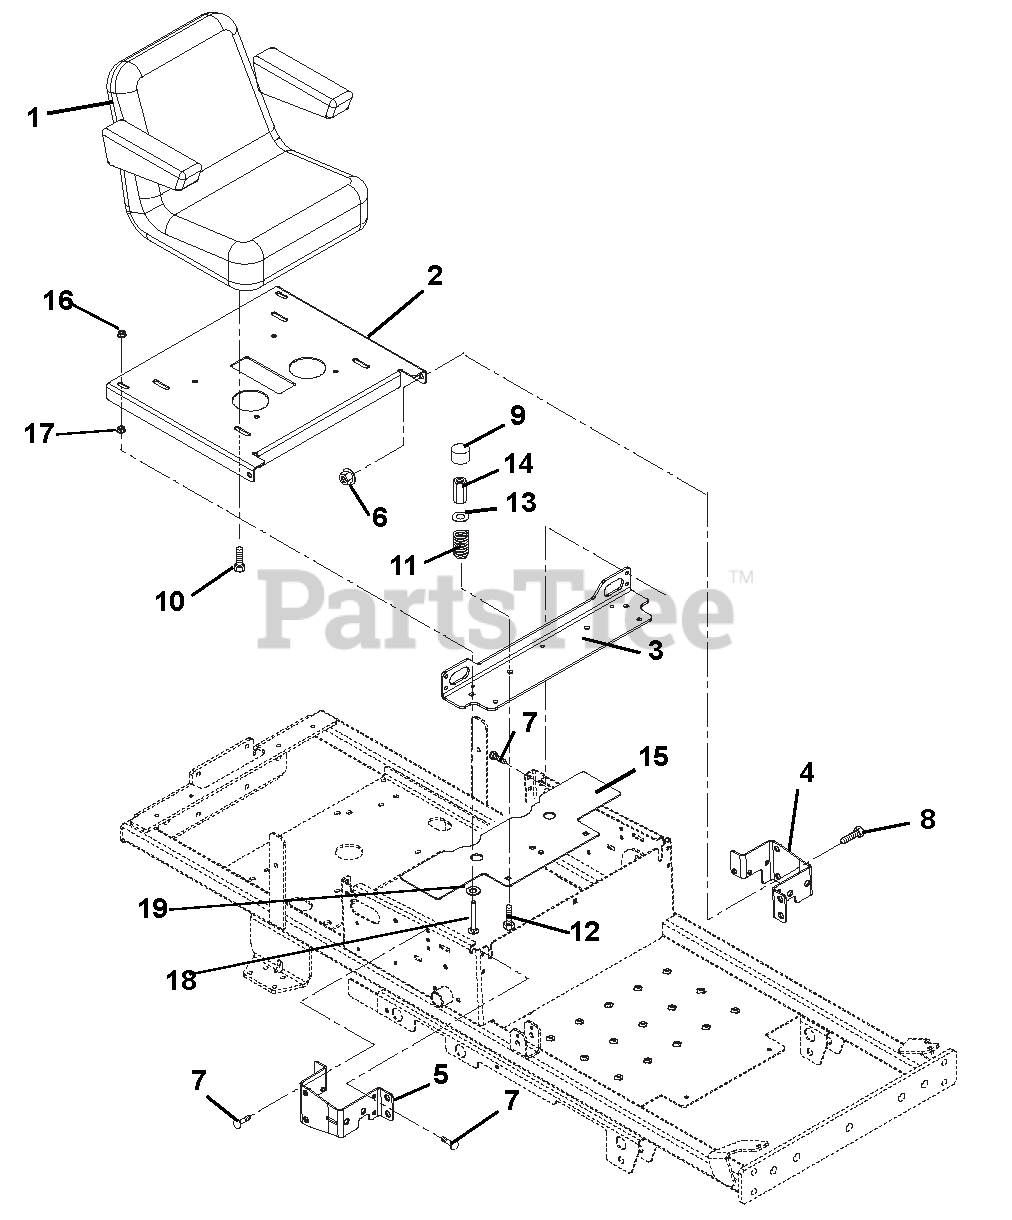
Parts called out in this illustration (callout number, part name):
1	SEAT, 1008 W/ARMREST SEATS INC
2	SEAT PLATE
3	BRKT, SEAT SPRING
4	WDMT, RH STEERING STOP
5	WDMT, LH STEERING STOP
6	@NUT-LK-TOP-FLG .38-16 YWZC
7	@SCR-TAP .31-18X.50 HWH TR YWZ
8	BOLT-SHLDR .375-16X.150
9	HUB CAP
10	5/16-18X3/4 HX/W/HD WHIZ
11	SPRING, SEAT
12	@BLT-RDHDSQNK .31-18X1.50 G5YZ
13	WSHR-FL-STL .328X.87X.179 YWZC
14	NUT, COUPLING 5/16-18 X 1 3/4
15	GUARD, ZOOM FINGER
15	BRKT, REAR FAN GUARD-CE ZOOM
16	@NUT-LK-NYL-FLG .31-18 YWZC
17	@NUT-SPNLK-FLG .312-18 YWZC
18	@BLT-RDHDSQNK .31-18X3.50 G5YZ
19	WSHR-FL-STL .505X1.00X.062YWZC
20	BRKT, SIDE FINGER GUARD - ZOOM
21	@NUT-LK-TOP-FLG .31-18 YWZC
22	@BLT-RHDSSQNK .31-18X1.00 G5YZ
